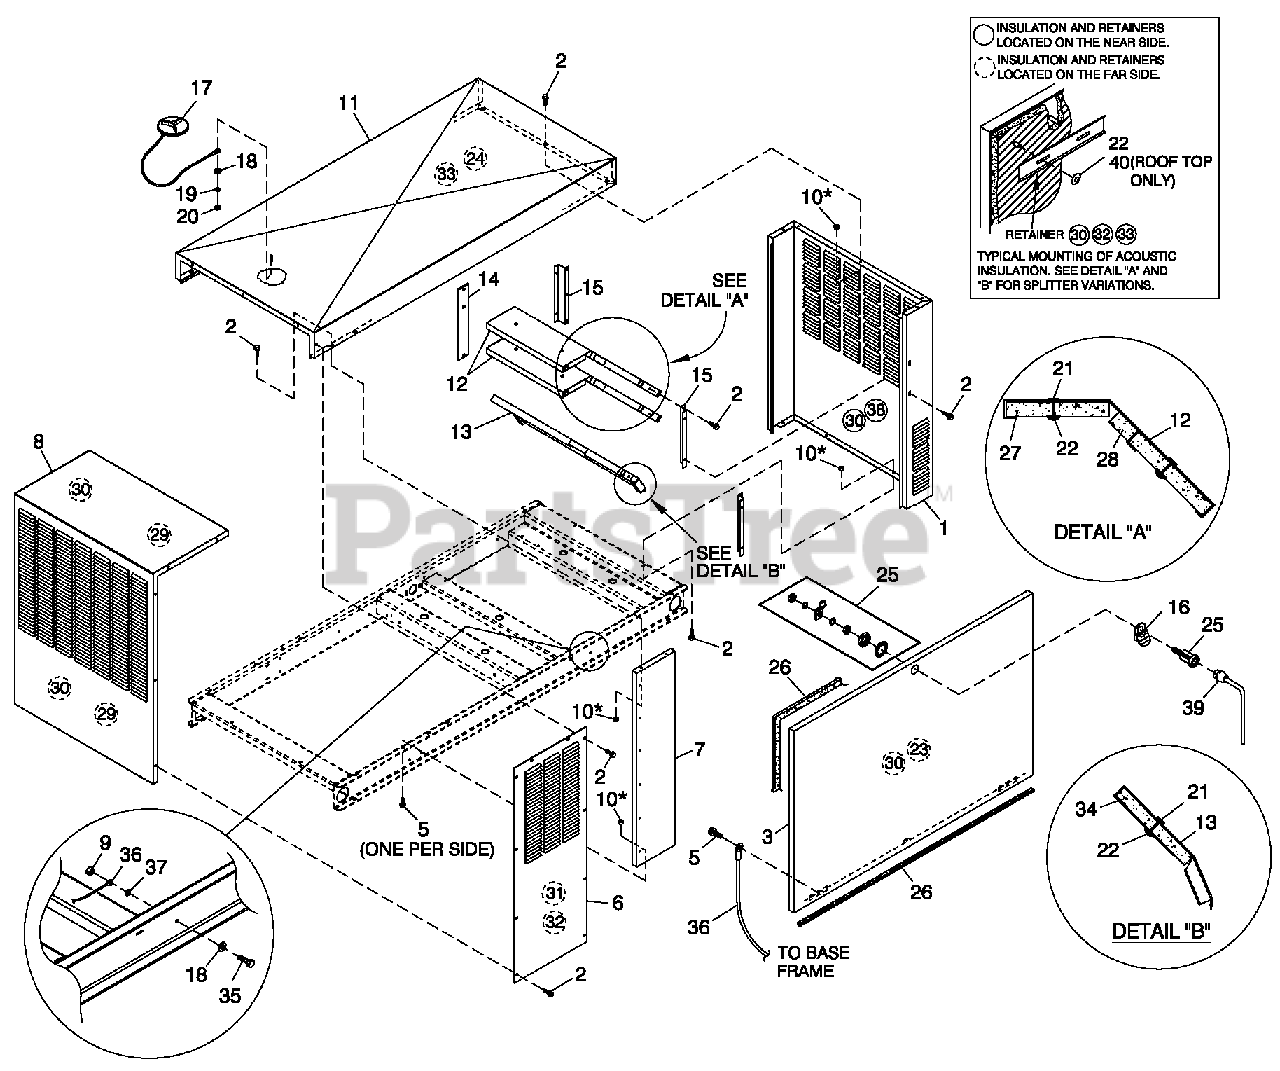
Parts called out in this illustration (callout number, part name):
1	REAR WRAP C2 CPL
1O	NUT HEX LOCK M6-1.O SS NY INS
2	SCREW THF M6-1 X 16 N WA Z/JS
2O	NUT HEX 1/4-2O STEEL
3	DOOR C2
3O	RETAINER INSULATION (82O)
4	RIVET POP .1875X.45OSS
4O	WASHER SELF LOCKING DOME #8-32
5	SCREW TH-FRM M6 W/CAP SHKPRF W
6	DISCHARGE DUCT LH & RH SIDE C2
7	FRONT CORNERS C2
8	DISCHARGE CENTER DUCT C2
9	NUT HEX M6X 1.O G8YEL CHR
11	ROOF C2
12	SLITTER C4
13	SPLITTER LOWER C4
14	SPLITTER STINGER C2
15	SUPPORT SPLITTER LH C2
16	TAB PULL
17	ASSEMBLY COVER ACCESS
18	WASHER FLAT 1/4-M6 ZINC
19	WASHERLOCK M6-1/4
21	INSULATION RETAINMENT HANGER
22	WASHER SELF LOCKING DOME #4-4O
23	INSULATION DOOR C2
24	INSULATION ROOFTOP
25	VISE-ACTION LATCH SLOTTED CIR
26	GASKET EXTRUDED TRIM (328" LG)
27	INSULATION SPLITTER
28	INSULATION SPLITTER
29	INSULATION DUCT
31	INSULATION DUCT SIDES
32	RETAINER INSULATION (45O)
33	RETAINER INSULATION (74O)
34	INSULATION LOWER SPLITTER
35	SCREW HHC M6-1.OX2O G8.8
36	ASSY WIRE 14 AWG 34.8" GRN/YEL
37	WASHER SHAKEPROOF INT 1/4
38	INSULATION REAR WRAP
39	KEY VISE-ACTION LATCH SLOT CIR
